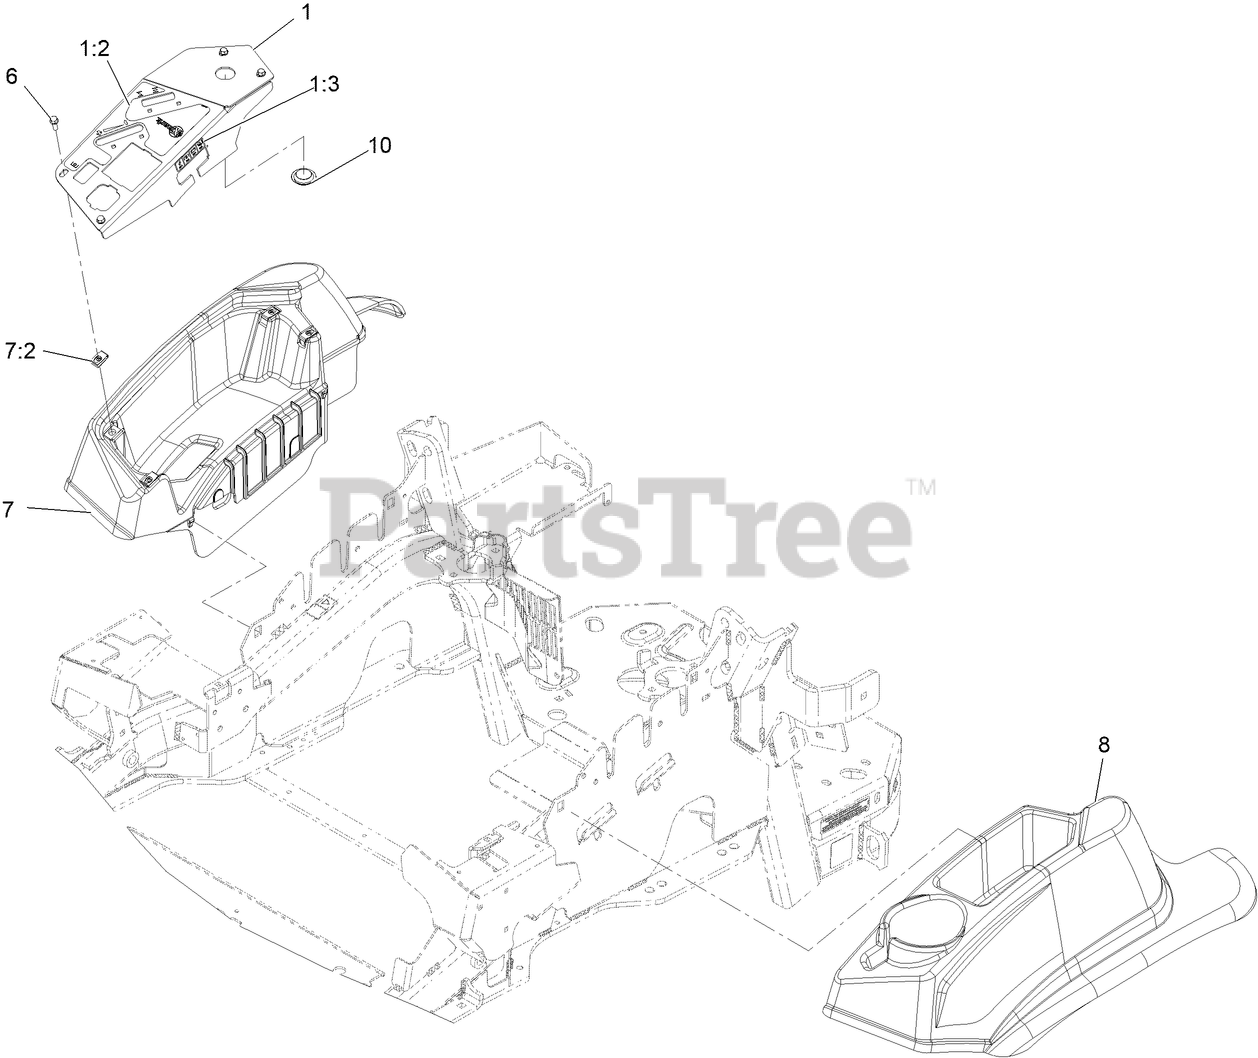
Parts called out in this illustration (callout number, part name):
1	ASM, Control Panel W/Decal
1:2	Decal, Control Panel Lazer
1:3	DECAL-FUSES
6	SCREW-HWH
7	CONSOLE,RH AS ASM
8	CONSOLE, LH AS
10	PLUG-PLASTIC
